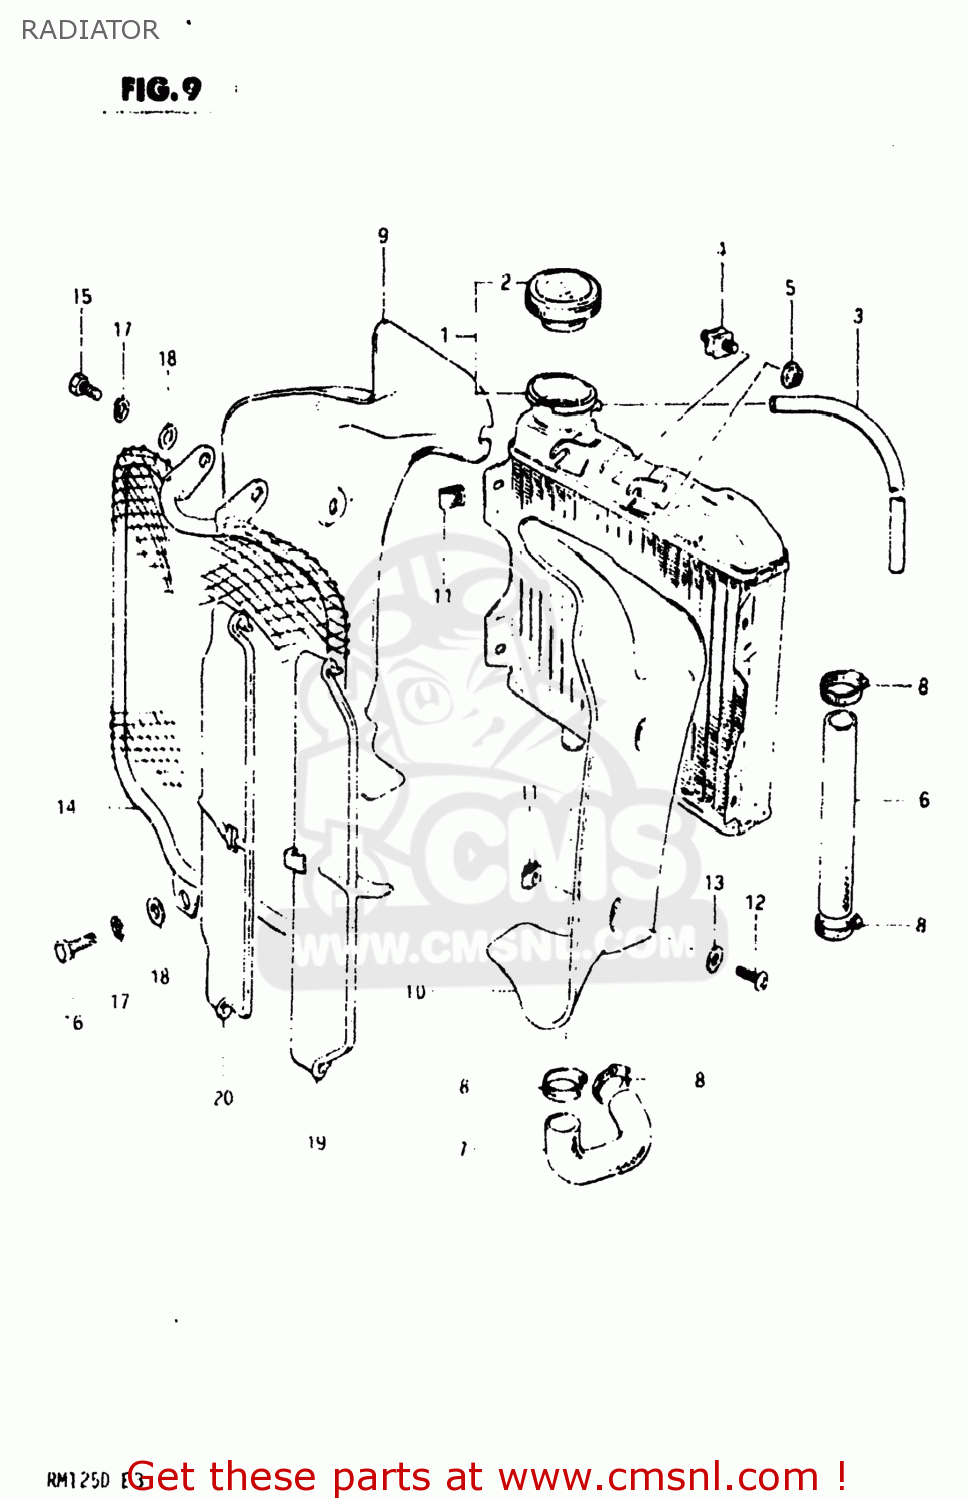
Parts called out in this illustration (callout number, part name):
1	RADIATOR ASSEMBLY,WATER
2	CAP,RADIATOR
3	HOSE,BREATHER
4	CUSHION,RADIATOR
5	NUT
6	HOSE,RADIATOR
7	HOSE,RADIATOR OUTLET
8	CLAMP
9	COVER,RADIATOR,R
10	COVER,RADIATOR,L
11	PLATE,RADIATOR COVER F
12	SCREW
13	WASHER (6.5X18X1.6)
14	BUMPER,RADIATOR
15	BOLT
16	BOLT
17	LOCK WASHER
18	WASHER,8.5X16X
19	LOUVER,RADIATOR MUD GUARD
20	LOUVER, MUDGUARD INNER
